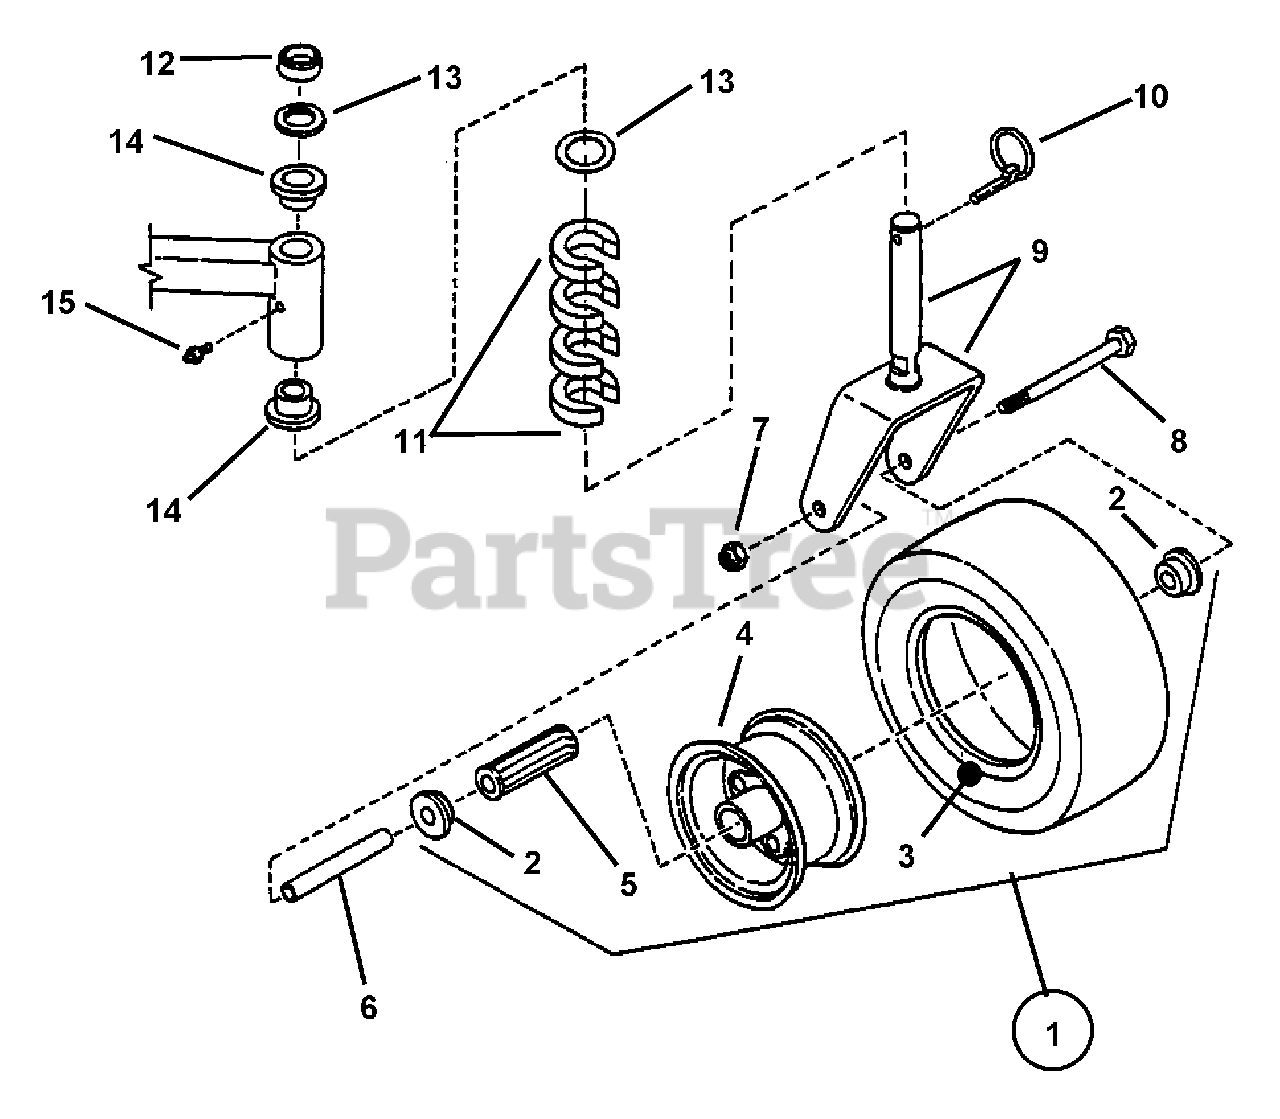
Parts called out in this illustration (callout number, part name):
1	ASSEMBLY, Wheel & Tire
2	RETAINER, Flanged
3	TIRE, 9 x 3.50 - 4
4	ASSEMBLY, Wheel
5	BEARING, Roller
6	SLEEVE, Axle
7	NUT, 1/2-13 HEX NYLON LOCK
8	BOLT, 1/2-13 X 5-1/2" GD5 YZ
9	YOKE, Caster Weldment
10	PIN, Lynch 7/16" Heavy Duty
11	SPACER
12	SPACER, 1" x 1 3/8 x .30" (PM)
13	BUSHING, 1"
14	BUSHING, Caster
15	FITTING, Lube
